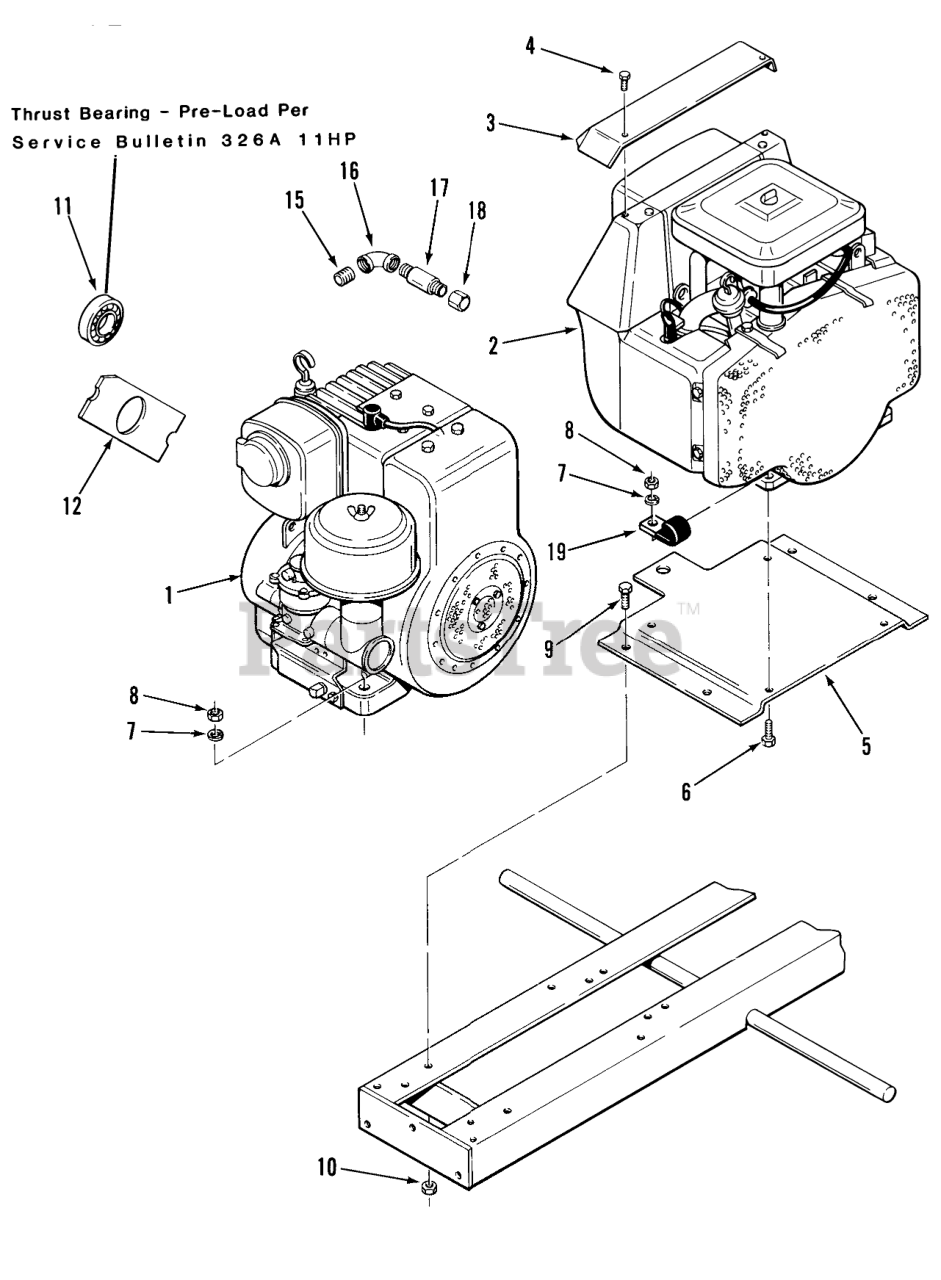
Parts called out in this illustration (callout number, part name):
1	Engine-11HP-B&S Model 252417, Type 0664-01
2	Engine-16HP-B&S Model 402437, Type 0694-01 GT-1600
2	Engine-18HP-B&S Model 422437, Type 0663-01 GT-1800
3	SHIELD HEAT
4	Bolt
5	BASE ENGINE R
5	BASE-ENGINE
6	HHCS
6	Bolt
7	Lockwasher
8	Nut
9	BOLT
10	Nut
11	BEARING-BALL
12	PLATE-THRUST B
15	Nipple 3/8
16	Elbow 3/8
17	Nipple 3/8 X 7
18	Cap
19	CLIP
